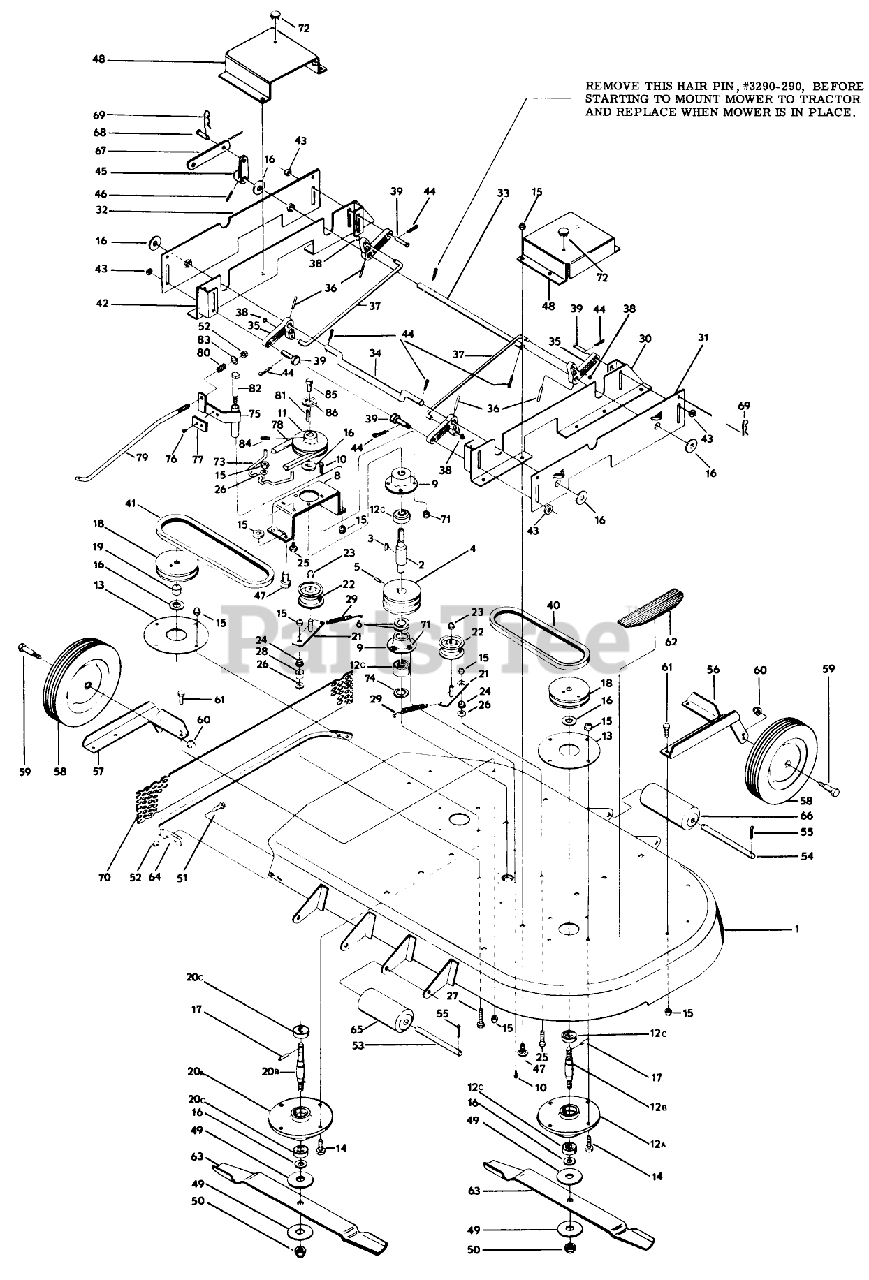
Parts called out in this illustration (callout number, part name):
1	Housing
2	BLADE DRIVE SHAFT
3	KEY-WOODRUFF
4	Pulley
5	Set Screw
6	Washer
7	Bearing
8	Support
9	Housing
10	Sems Unit
11	Pulley
12	Left Hand Mower Spindle Assembly(Complete)(Consists of:)
12A	MOWER SPINDLE HOUSING
12B	LH BLADE SHAFT
12C	Bearing
13	Washer
14	SCREW-HH
16	Washer
18	Pulley
19	Spacer
20	Right Hand Mower Spindle Assembly(Complete)(Consists of:)
20A	MOWER SPINDLE HOUSING
20B	Blade Shaft
20C	Bearing
21	Idler Arm
22	Pulley
23	NUT-JAM
24	Bushing
25	SCREW-HH
26	WASHER-FLAT
27	SCREW-HH
28	Spacer
29	IDLER ARM SPRING
30	Bracket Assy. Lower
31	Mower Plate Housing
32	Mower Plate Housing
33	Rear Pivot Shaft
34	Front Pivot Shaft
35	Bell Crank
36	Roll Pin
37	Lift Link
38	RING-RETAINING, EXT
39	Lift Pin
41	Belt
42	Bracket Assy. Lower
43	Washer
44	PIN-COTTER
45	Lever
47	Screw
48	Cover
49	WASHER
50	Nut
51	SCREW-CARR
52	Nut
53	ROLLER SHAFT
54	ROLLER SHAFT
55	PIN-COTTER
56	Bracket
57	Bracket
60	Nut
61	SCREW-HH
62	Foot Pad
63	Blade
64	Guard
65	Roller
66	Roller
67	Adjusting Link
68	Pin
69	PIN-COTTER, HAIR
70	Mulcher
71	Self Clinching Nut
72	Button Plug
73	Belt Guide
74	Spacer
75	a. Bracket
77	BLADE BRAKE LINING
78	V-BELT
79	Brake Rod
80	Spring
81	KEY-SQUARE
82	Shoulder Bolt
83	Washer
84	Set Screw
85	SCREW-HH
86	Washer
